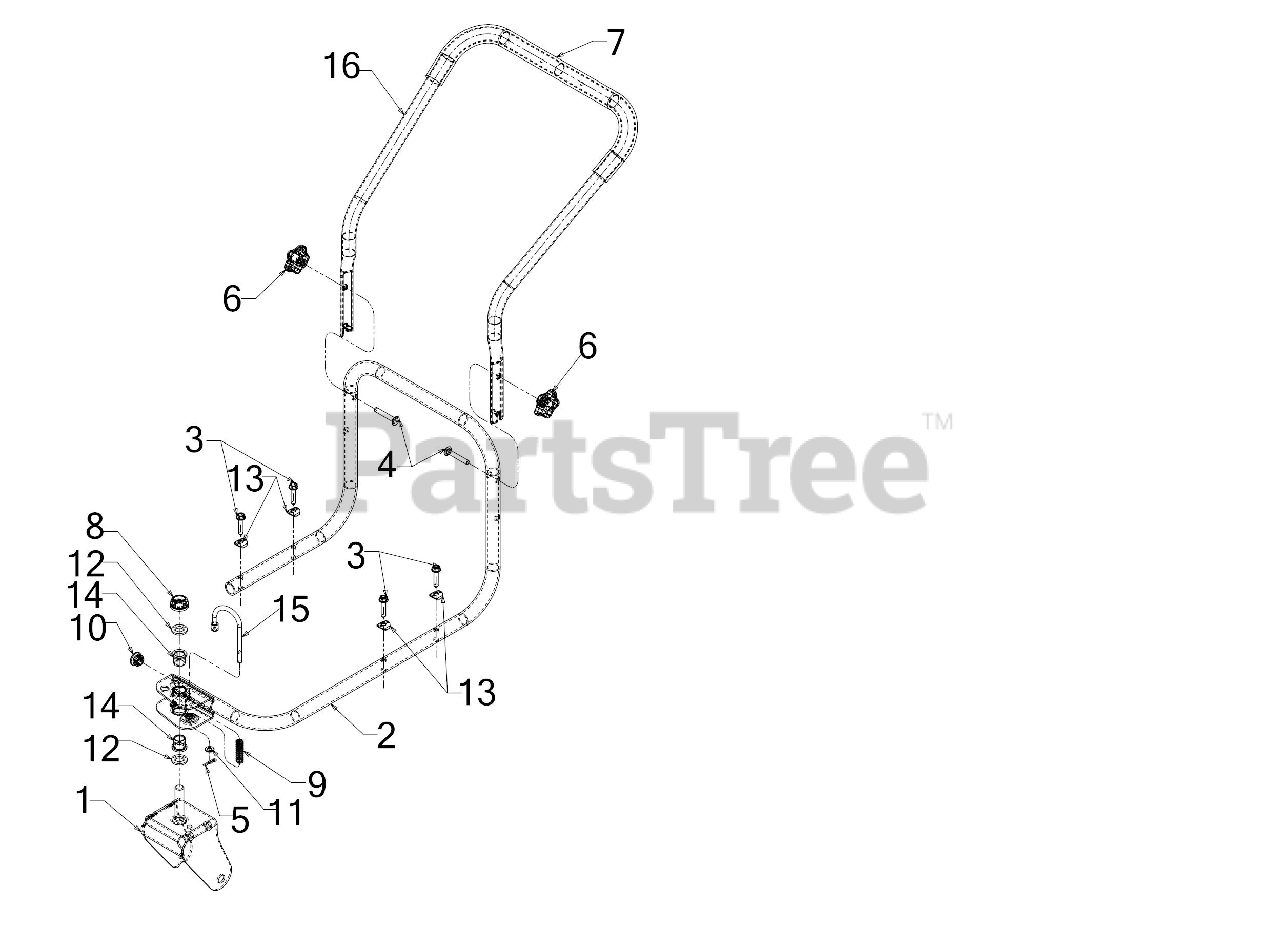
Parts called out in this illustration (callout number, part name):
1	WHEEL BRACKET ASSEMBLY
2	LOWER HANDLE ASSEMBLY
3	HEX SCREW WASHER 5/16-18 x 1.5
4	BOLT 5/16-18 x 2.00 GR5
5	COTTER PIN .072 DIA
6	STAR KNOB 5/16-18
9	COMPRESSION SPRING
11	FLAT WASHER
12	FLAT WASHER
13	SADDLE WASHER
14	BEARING:FLANGE .631 ID
16	UPPER HANDLE BLOWER
